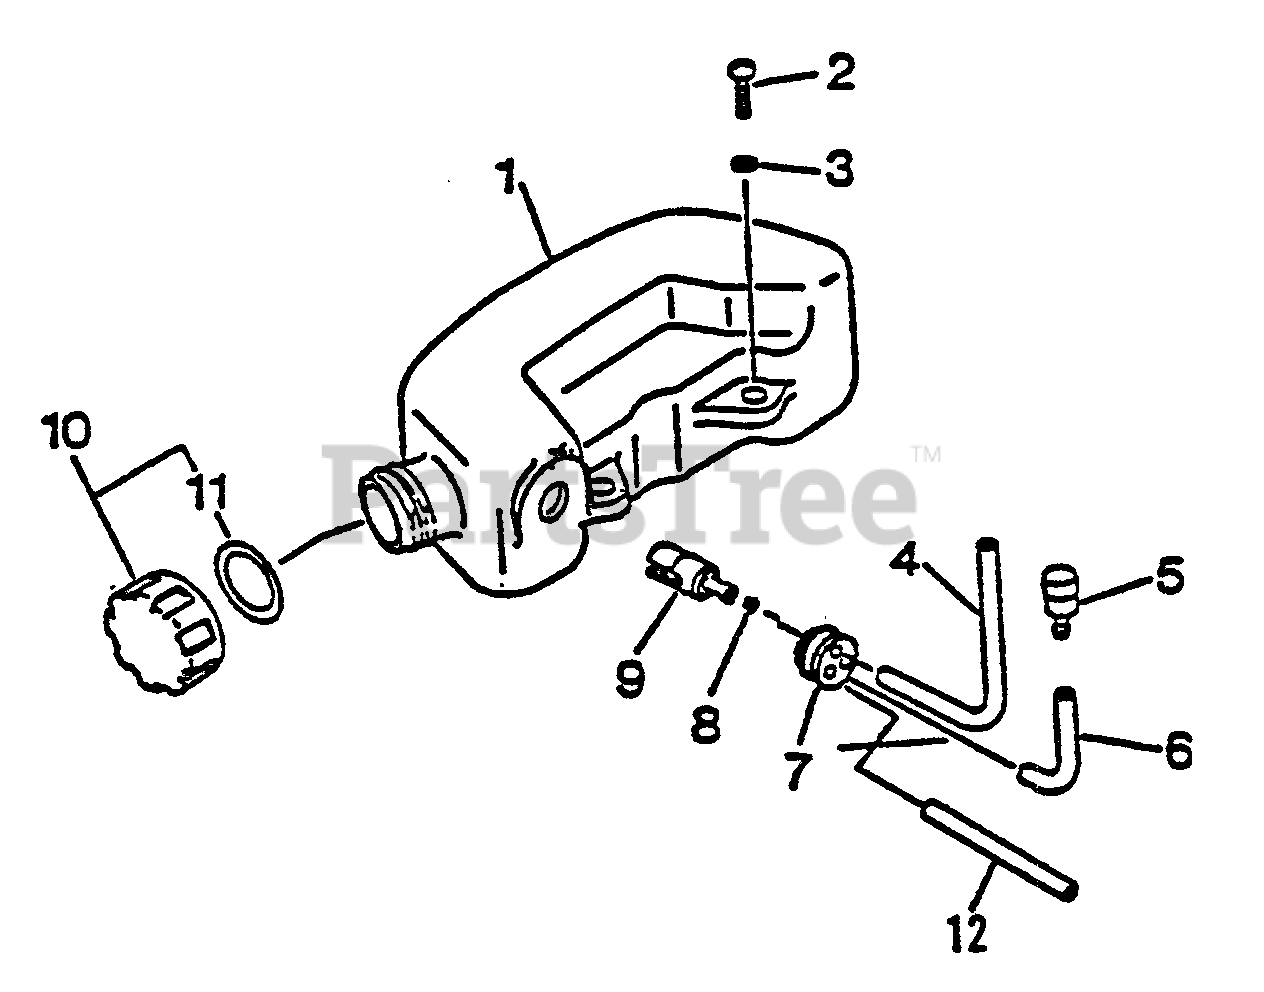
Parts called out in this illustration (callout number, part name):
1	TANK, FUEL
2	SCREW - 5X16
3	WASHER - 5
4	PIPE - 3X5X195 -- BLACK
5	VENT, FUEL TANK
6	PIPE - 3X6X70 -- CLEAR
7	GROMMET
8	CLIP - 6
9	FILTER, FUEL
10	CAP ASSY
11	GASKET, CAP
12	PIPE - 3X6X110 -- CLEAR
